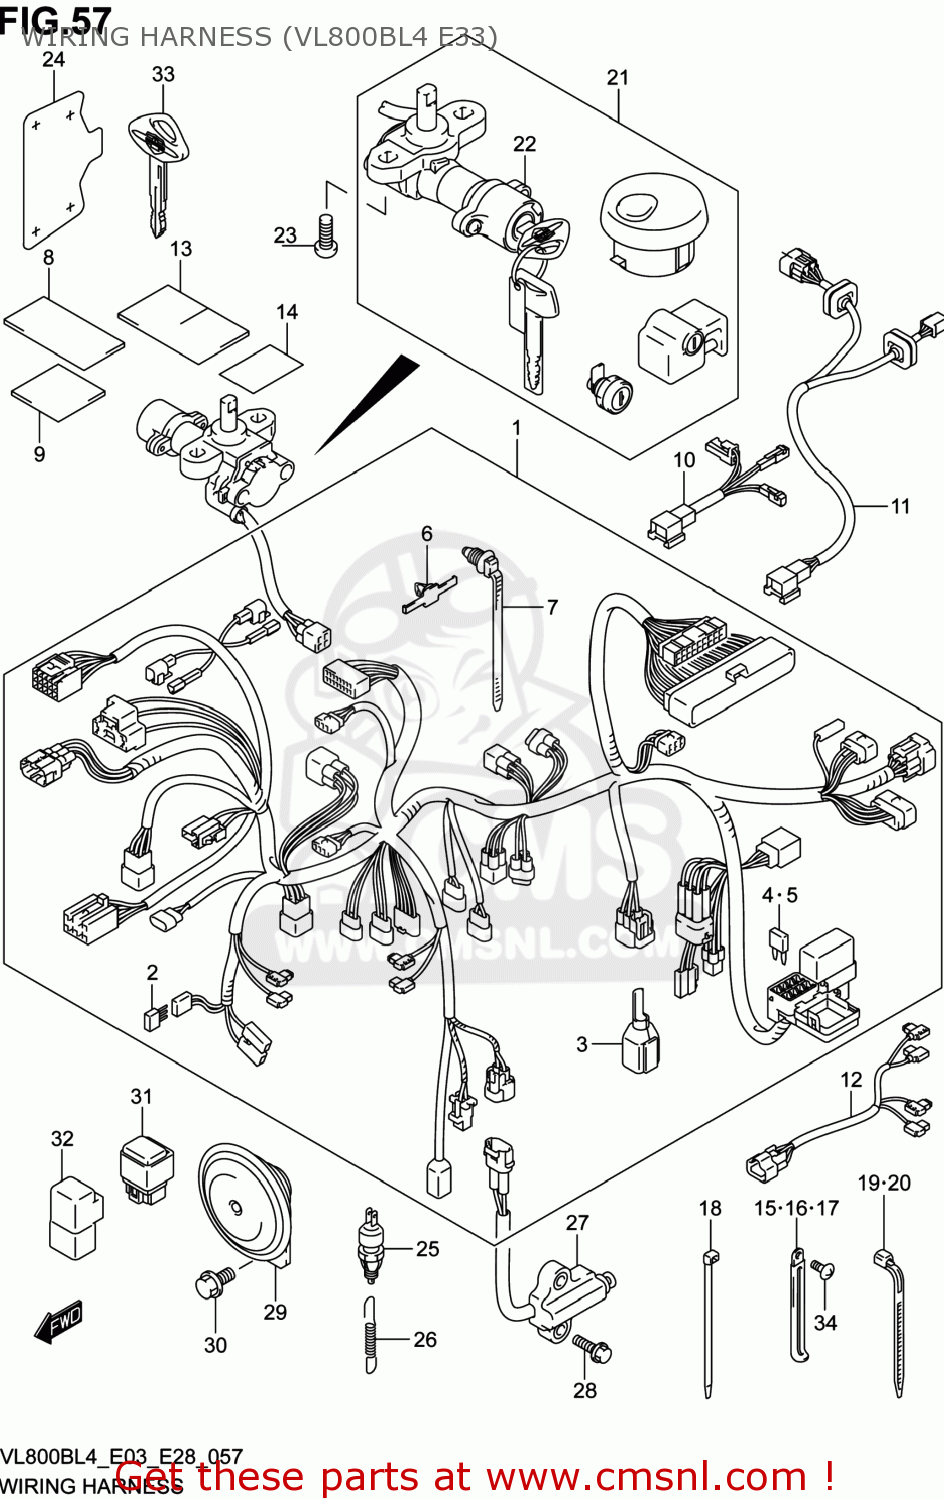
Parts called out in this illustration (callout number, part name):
1	HARNESS,WIRING
2	RECTIFIER ASSY
3	BOOT
4	FUSE(10A)
5	FUSE(20A)
6	CLAMP
7	CLAMP(L:154)
8	TAPE,WIRING HARNESS(28X50X0.13
9	PROTECTOR,WIRING HARNESS
10	WIRE,RR COMB NO.2
11	WIRE,RR COMB
12	WIRE,IGNITION COIL LEAD
13	PROTECTOR,HARNESS(30X50X3)
14	PROTECTOR,COWLING UNDER
15	CLAMP(L:45)
16	CLAMP(L:80)
17	CLAMP(L:135)
18	CLAMP(L:145)
19	CLAMP(L:165)
20	CLAMP(L:190)
21	LOCK SET
22	LOCK ASSY,STEERING
23	BOLT(8X20)
24	PROTECTOR,IGNITION SWITCH
25	SWITCH ASSY,STOP LAMP
26	SPRING
27	SWITCH ASSY,SIDE STAND
28	BOLT(6X20)
29	HORN ASSY
30	BOLT
31	RELAY ASSY
32	RELAY ASSY
33	KEY,BLANK(BOULEVARD)
34	SCREW
